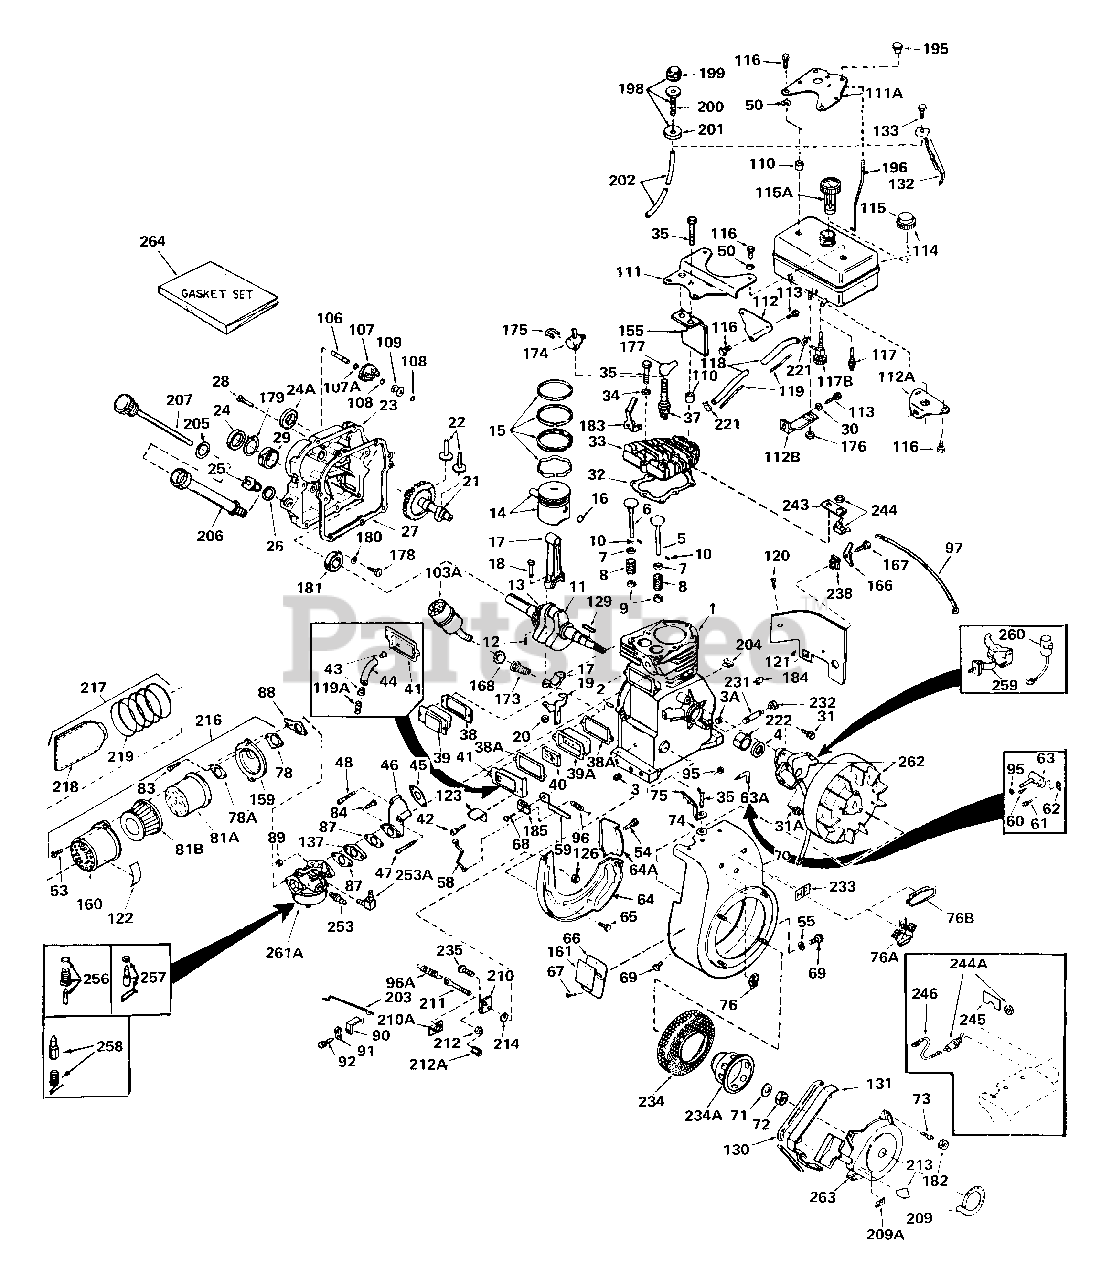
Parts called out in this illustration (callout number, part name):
1	"Cylinder Assy. (2-1/2" Bore)
2	Pin, Dowel
3	Plug, Oil drain (Square hd.) (1/4-18)
3A	Plug, Oil drain (Square hd.) (1/4-18)
4	Seal, Oil
5	Valve, Intake (Standard)
5	Valve, Intake (1/32" oversize)
6	Valve, Exhaust (Standard)
6	Valve, Exhaust (1/32" oversize)
7	Cap, Upper valve spring
8	Spring, Valve
9	Cap, Lower valve spring
11	Crankshaft Assy.
12	Pin, Crankshaft gear
13	Gear, Crankshaft
14	Piston & Pin Assy. (Standard) (2-1/2" )
14	Piston & Pin Assy. (.010 oversize)
14	Piston & Pin Assy. (.020 oversize)
15	Ring Set, Piston (Standard) (2-1/2")
15	Ring Set, Piston (.010 oversize)
15	Ring Set, Piston (.020 oversize)
16	Ring, Piston pin retaining
17	Rod Assy., Connecting
18	Bolt, Connecting rod
19	Dipper, Oil
20	Nut, Connecting rod bolt
21	Camshaft (No compression release)
22	Lifter, valve
23	Cover, Cylinder
24	Seal, Oil
25	Plug, Oil filler
26	Gasket, Oil filler
27	Gasket, Cylinder cover
28	Screw
29	Bushing, Crankshaft
30	Washer, Flat
32	Gasket, Cylinder head
33	Head, Cylinder
35	Head bolt, Hex hd. cap, 5/16-18 x 1-1 /4
35	Head bolt, Hex hd. cap, 5/16-18 x 2
35	Head bolt, Hex hd. cap, 5/16-18 x 2-1 /4
37	Plug, Spark (Champion J-8 or equivale nt)
38	Gasket, Breather
39	Breather Assy.
40	Element, Breather
45	Gasket, Intake pipe (1/32" thick)
47	Screw, Phil. fil. hd. Sems, 1/4-20 x 1-19/32
48	Screw, Phil. fil. hd. Sems, 1/4-20 x 1-3/8
48	Screw, Fil. flex hd. self-locking, 1/ 4-20 x
48	Screw, Phil. fil. hd. Sems, 1/4-20 x 1-19/32
50	Lockwasher, 1/4"
50	Washer, Flat 5/16"
53	Screw, Fil. slotted hd. Sems, 8-32 x 3/8
53	Screw, Fil. hd mach., 8-32 x 5/16
64	Baffle, Blower housing
65	Screw, Hex hd. self-tap Sems, 10-24 x 9/16
65	Screw, Phil. hex hd. Sems, 1/4-20 x 5 /8
66	Plate, Identification
67	Stud, Drive
68	Screw
69	Screw
70	Housing, Blower
71	Washer, Belleville
72	Nut, Flywheel
73	Screw, Phil. pan hd. Sems, 1/4-28 x 7 /16
74	Lockwasher
75	Clip, Shorting
76	Decal, Name & H.P. (2-1/4 H.P.)
76	Decal, Name & H.P. (3 H.P.)
76	Decal, Name & H.P. (3-1/2 H.P.)
76	Decal, Name & H.P. (2-1/2 H.P.)
76	Decal, Name & H.P. (4.0)
76A	Decal, Mini-Bike (2-1/2 H.P.)
76A	Decal, Mini-Bike (3 H.P.)
76A	Decal, Mini-Bike (3-1/2 H.P.)
78	Gasket, Air cleaner
78A	Spacer, Cleaner
83	Screw, Phil. fil. hd. mach., Sems, 10 -32 x
83	Screw, Fil. hd. Sems, 10-32 x 3/4
83	Screw, Phil. fil. hd. Sems, 10-32 x 5 /8
83	Screw, Rd. phil. hd., 10-32 x 7/16
84	Screw, Hex hd. cap, 1/4-28 x 7/8
84	Screw, Hex hd. cap, 1/4-28 x 1
84	Screw, Hex hd. cap, Sems, 1/4-20 x 1
84	Screw, Hex hd. cap, 1/4-28 x 1-1/4
87	Gasket, Carburetor (1/8" thick)
88	Bracket, Boden wire
89	Nut & Lockwasher
90	Bracket, Speed limit
91	Clip, Conduit
92	Screw, Hex hd. slotted Sems, 10-32 x 3/8
95	Washer, Flat
106	Shaft, Mechanical governor
107A	Washer, Flat
108	Ring, Retaining
111A	Bracket, Upper fuel tank
113	Screw, Hex hd. cap, Sems, 1/4-20 x 1/ 2
113	Screw, Hex hd. cap, 1/4-20 x 1/2
113	Screw, Phil. hex hd. Sems, 1/4-20 x 5 /8
114	Tank Assy., Fuel (Charcoal Poly) (1 q t.)
115	Cap, Fuel filler (Special bayonet typ e)
115	Cap, Fuel filler (Red Plastic) (Sno-p roof)
115	Cap, Fuel filler (Charcoal Plastic) ( Spurt
115	Cap, Fuel filler (Charcoal Plastic)
115	Cap, Fuel filler (Red Plastic) (Spurt proof)
115	Cap, Fuel filler (Plastic) (Standard)
116	Screw, Hex slotted hd. Sems, 1/4-28 x 5/8
116	Screw, Hex hd. Sems, 1/4-14 x 7/8"
116	Screw, Hex hd. cap, 5/16-18 x 2-1/2"
117	Strainer & Fitting, Fuel
117B	Fitting & Shut-off
117B	Valve, Fuel shut-off
118	Line, Fuel (Braided hose) (8.25")
118	Line, Fuel (Braided hose) (16")
118	Line, Fuel (Braided hose) (32")
119	Spring, Fuel line (11/64" Dia.)
119A	Spring, Breather tube (1/4" Dia.)
121	Extension, Blower housing
126	Locknut
129	Key, Flywheel
130	Seal, Snow guard
131	Guard, Starter
132	Baffle, Heat
133	Screw, Hex washer hd. thr'd., 10-24 x 1/2
137	Spacer, Carburetor
155	Baffle, Heat
161	Decal, Instruction Spec. Nos. 35006F, 6G,
161	Decal, Instruction
161	Decal, Instruction Spec. Nos. 25205H, 212H,
166	Terminal, Ground (Two male terminal t abs)
167	Screw, Hex hd. slotted thr'd, 8-32 x 5/16
167	Screw, Hex hd. cap Sems, 1/4-20 x 1/2
167	Screw, Phil. hex hd. Sems, 1/4-20 x 5 /8
167	Screw, Phil. pan hd. thr'd, 8-18 x 3/ 8
168	Nut, Conduit
177	Cover, Spark plug
178	Screw, Hex hd. self-tap, Sems, 10-24 x 9/16
179	Ring, Retaining (All ball bearing mod els)
180	Washer, Flat (All ball bearing models )
181	Bearing, Ball All ball bearing models except
183	Clip, Spark plug shorting
184	Clip, Fuel line
185	Clamp, Governor lever
203	Link, Bellcrank
204	Clip, Wire retaining
209	Decal, Super-start (Round)
209A	Decal, Super-start
213	Decal, Ezee start
214	Lockwasher
216	Cleaner Assy., Air
217	Kit, Pre-cleaner
218	Bag, Pre-cleaner
219	Spring, Pre-cleaner
221	Clamp, Fuel line
222	Bushing, Crankshaft
231	Nipple, Oil drain (2-1/2")
231	Nipple, Oil drain (3-1/2")
232	Cap, Oil drain
233	Decal, H.P. (3 H.P.)
233	Decal, H.P. (3-1/2 H.P.)
233	Decal, H.P. (2-1/2 H.P.)
234	Screen, Starter cup
234A	Cup, Starter
235	Screw, Hex hd. slotted Sems, 10-32 x 3/8
235	Screw, Hex hd. self-tap Sems, 10-24 x 9/16
238	Grommet, Plastic
243	Bracket, Toggle switch
244	Switch, Toggle
258	Inlet Needle & Spring Assy.
259	Contact Assy., Breaker
260	Condenser
261A	Carburetor
262	Magneto, Tecumseh
263	Starter, Rewind
264	Gasket Set
